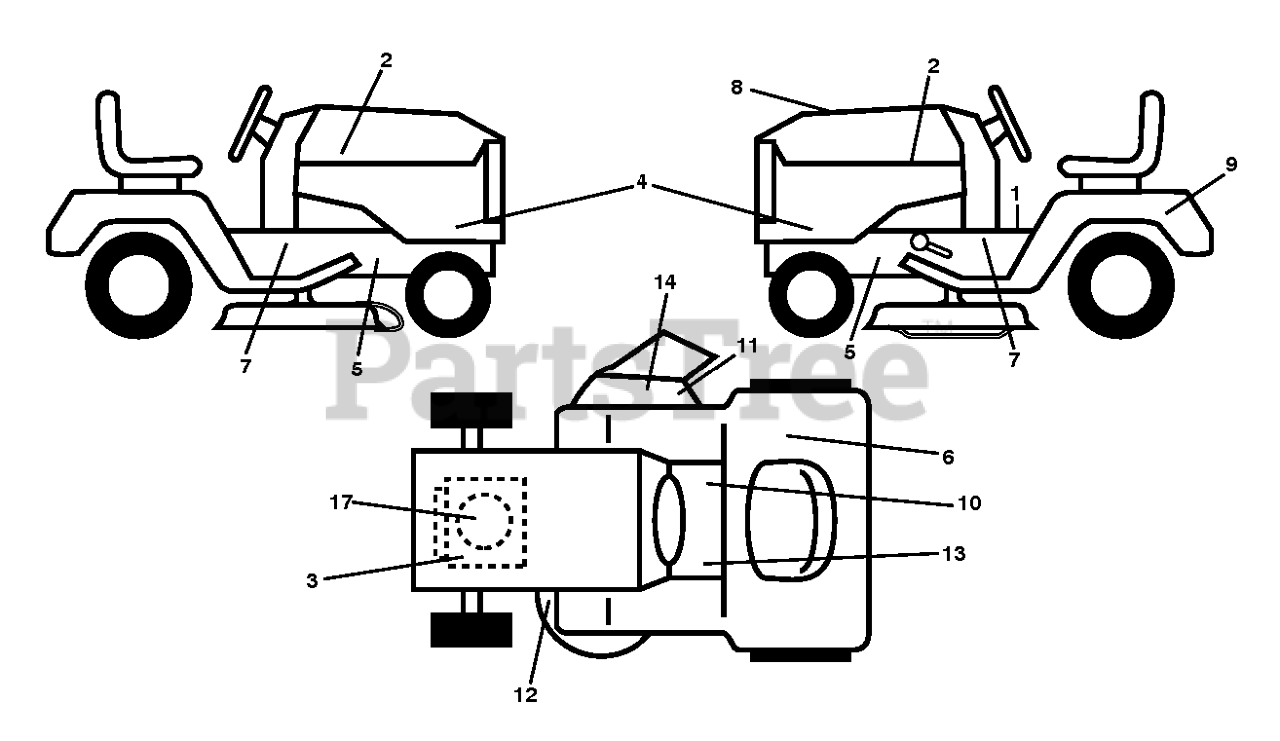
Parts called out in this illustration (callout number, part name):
1	DECAL.READ.OWN.MAN.SYMBOL.LT
2	DECAL.BADGE.170MM.TEXTLOGO.
3	DECAL.ENGINE.WARNING
5	DECAL.CHASSIS.HOT.MUFFLER
6	DECAL.CERTIFICATION.6MIL.100D
7	DECAL.WARNING.SERVCE/FIRE
8	DECAL DECAL.RPL.BSM21.PB.SRD.3
9	DECAL BTRY SYMBOLS
10	DECAL.PARKING.BRAKE.SADDLE.LT
11	DECAL.WARN.DFLCTR/CTFRG.SRD
12	DECAL.V.BELT.30"
13	DECAL.FNDR.SDLE.BRAKE.CLUTCH.6
17	DECAL
